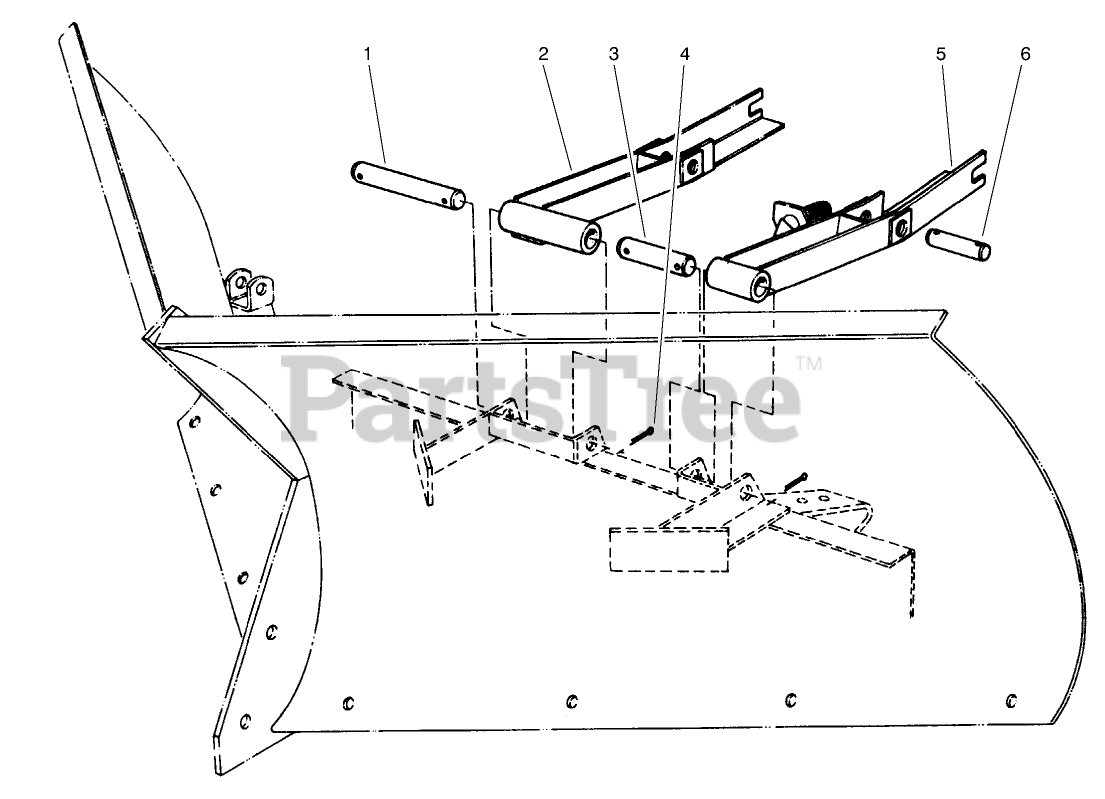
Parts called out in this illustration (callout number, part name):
1	PIN-PLAIN
2	RH PUSH ARM WA R
3	PIN-PLAIN
4	PIN-COTTER
5	LH PUSH ARM WA R
6	PIN R
